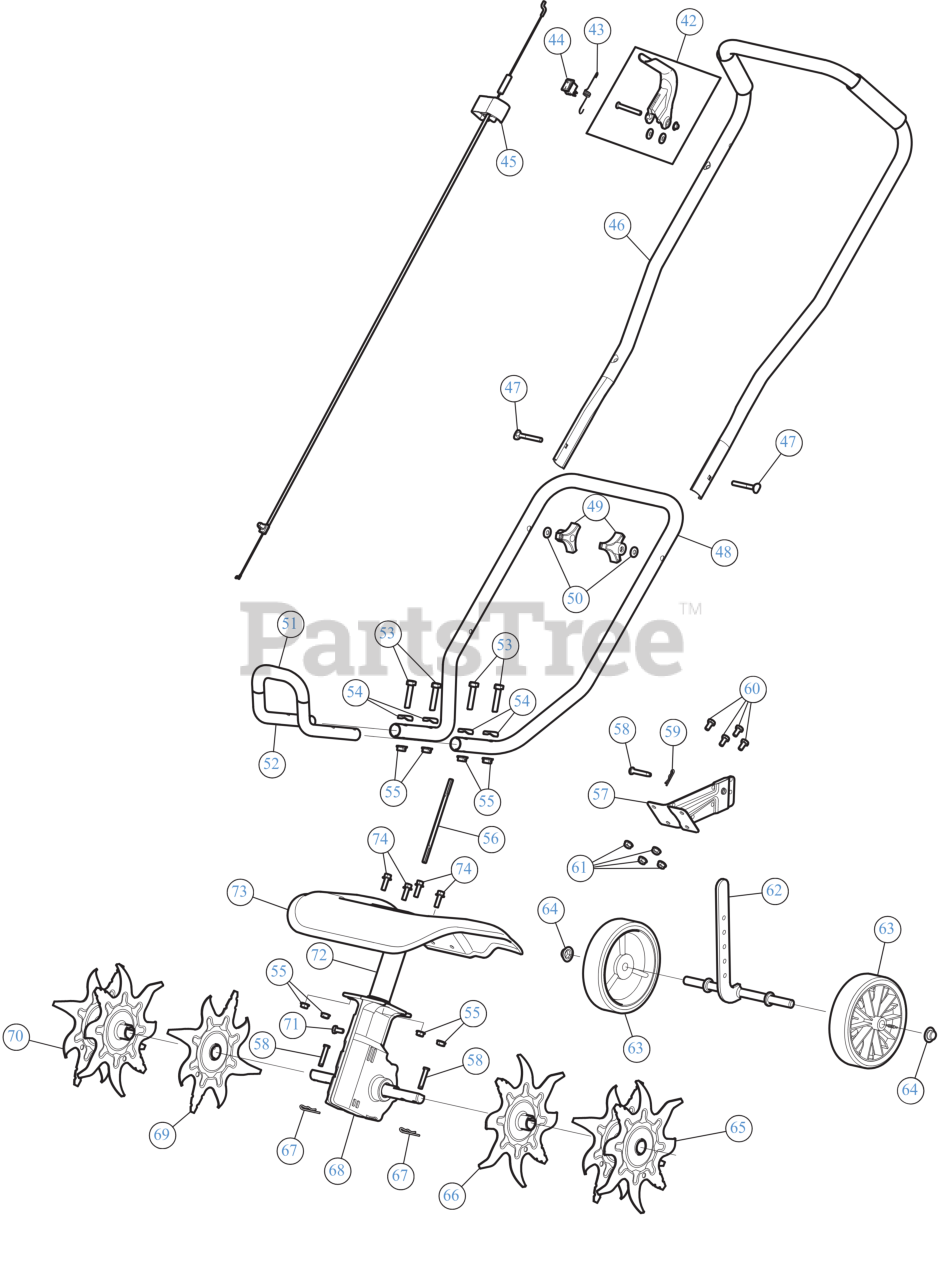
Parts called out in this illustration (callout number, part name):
42	THROTTLE LEVER
43	SPRING
44	SW, MOMENTARY ON/O
45	THROTTLE CABLE
46	HANDLE UPR CULT
47	BOLT, CARRIAGE CRV
48	LOWER HANDLE
49	KNOB, 3-PRONG ¼ "-
50	WASH, FLAT SPECIAL
51	FOAM GRIP - 9"
52	FRONT HANDLE
53	SCREW 5/16-18 x 1.5 LG
54	SADDLE WASHER
55	LOCK NUT 1/4
56	SHAFT-FLEX
57	TAILPIECE BRACKET ASSEMBLY
58	CLEVIS PIN
59	BOW TIE COTTER PIN 1/4-5/16
60	SCREW 1/4-20X.5 GR5
61	LOCK NUT 1/4
62	BRACKET ASSEMBLY
63	WHEEL 5-1.5 GRAY
64	PUSH CAP
65	TINE ASSEMBLY (LH)
66	TINE ASSEMBLY (LH)I (RH)O
67	BOW TIE COTTER PIN 1/4-5/16
68	GEARBOX ASSEMBLY CULT
69	TINE ASSEMBLY (LH)O (RH)I
70	TINE ASSEMBLY (RH)
71	SCREW 1/4-20 X.500
72	BOOM ASSEMBLY CULT
73	TINE SHIELD
74	HEX SCREW 1/4-20X.
